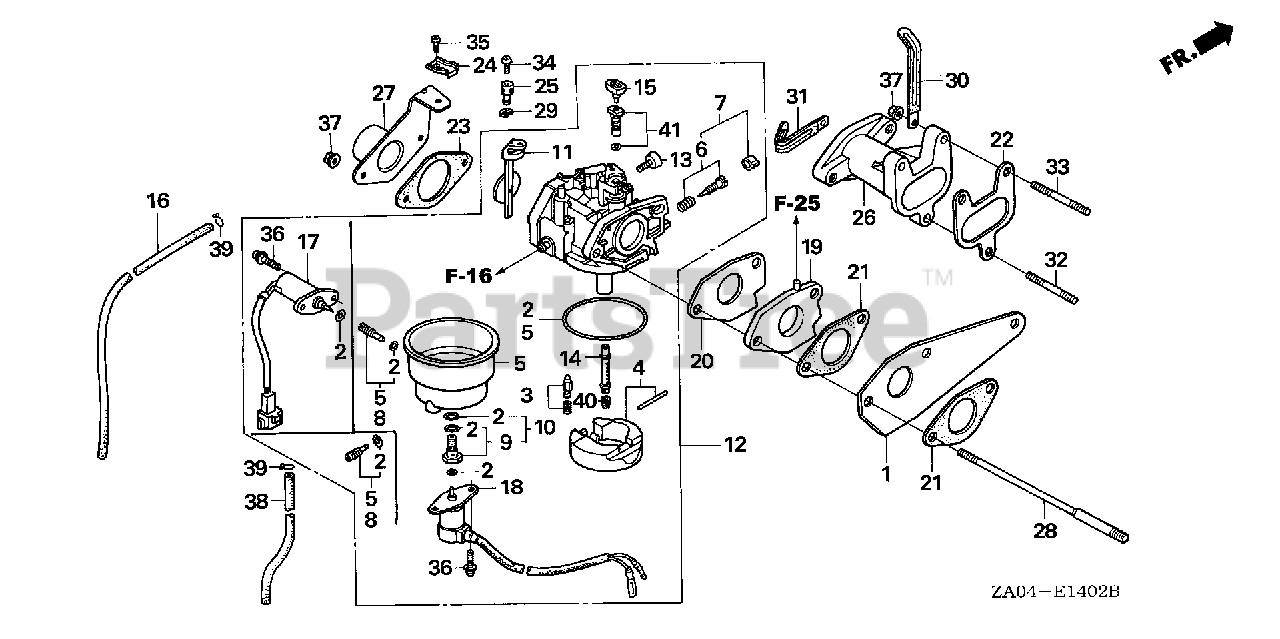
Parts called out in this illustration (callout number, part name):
1	STAY, TIMING BELT
2	GASKET SET (CARBURETOR NO.)
3	VALVE SET, FLOAT
4	FLOAT SET
5	CHAMBER SET, FLOAT (CARBURETOR NO.)
7	SCREW SET
8	SCREW SET, DRAIN (ADVENTURE GREEN) (CARBURETOR NO.)
10	SCREW SET
11	CHOKE SET
12	CARBURETOR ASSY. (BE77H B)
13	SCREW, THROTTLE STOP
14	NOZZLE, MAIN
15	COLLAR, SET
16	TUBE, AIR VENT
17	VALVE ASSY., SOLENOID (CARBURETOR NO.)
19	INSULATOR, CARBURETOR
20	GASKET, CARBURETOR
21	GASKET, INSULATOR
22	GASKET, IN. MANIFOLD
23	GASKET, AIR CLEANER
24	HOLDER, CONTROL CABLE Use from Engine SN 2327377.
25	HOLDER, CABLE
26	MANIFOLD, IN.
27	PIPE, AIR IN.
28	BOLT, STUD (8X100)
29	CIRCLIP (5MM) Use from Engine SN 2327377.
31	CLIP (6X20)
32	BOLT, STUD (6X32)
33	BOLT, STUD (6X28)
34	SCREW, PAN (4X8)
35	SCREW, PAN (5X10)
36	SCREW-WASHER (5X12)
37	NUT, FLANGE (6MM)
38	BULK HOSE, FUEL (4.5X3000) (Honda Code 5137104). (4.5X140)
39	CLIP, TUBE (B8)
40	JET, MAIN (#88) Use up to Engine SN BE81B B.
40	JET, MAIN (#90) Use from Engine SN BE81B C.
40	JET, MAIN (#92)
41	JET SET, PILOT (#40) (ADVENTURE GREEN) (CARBURETOR NO.)
